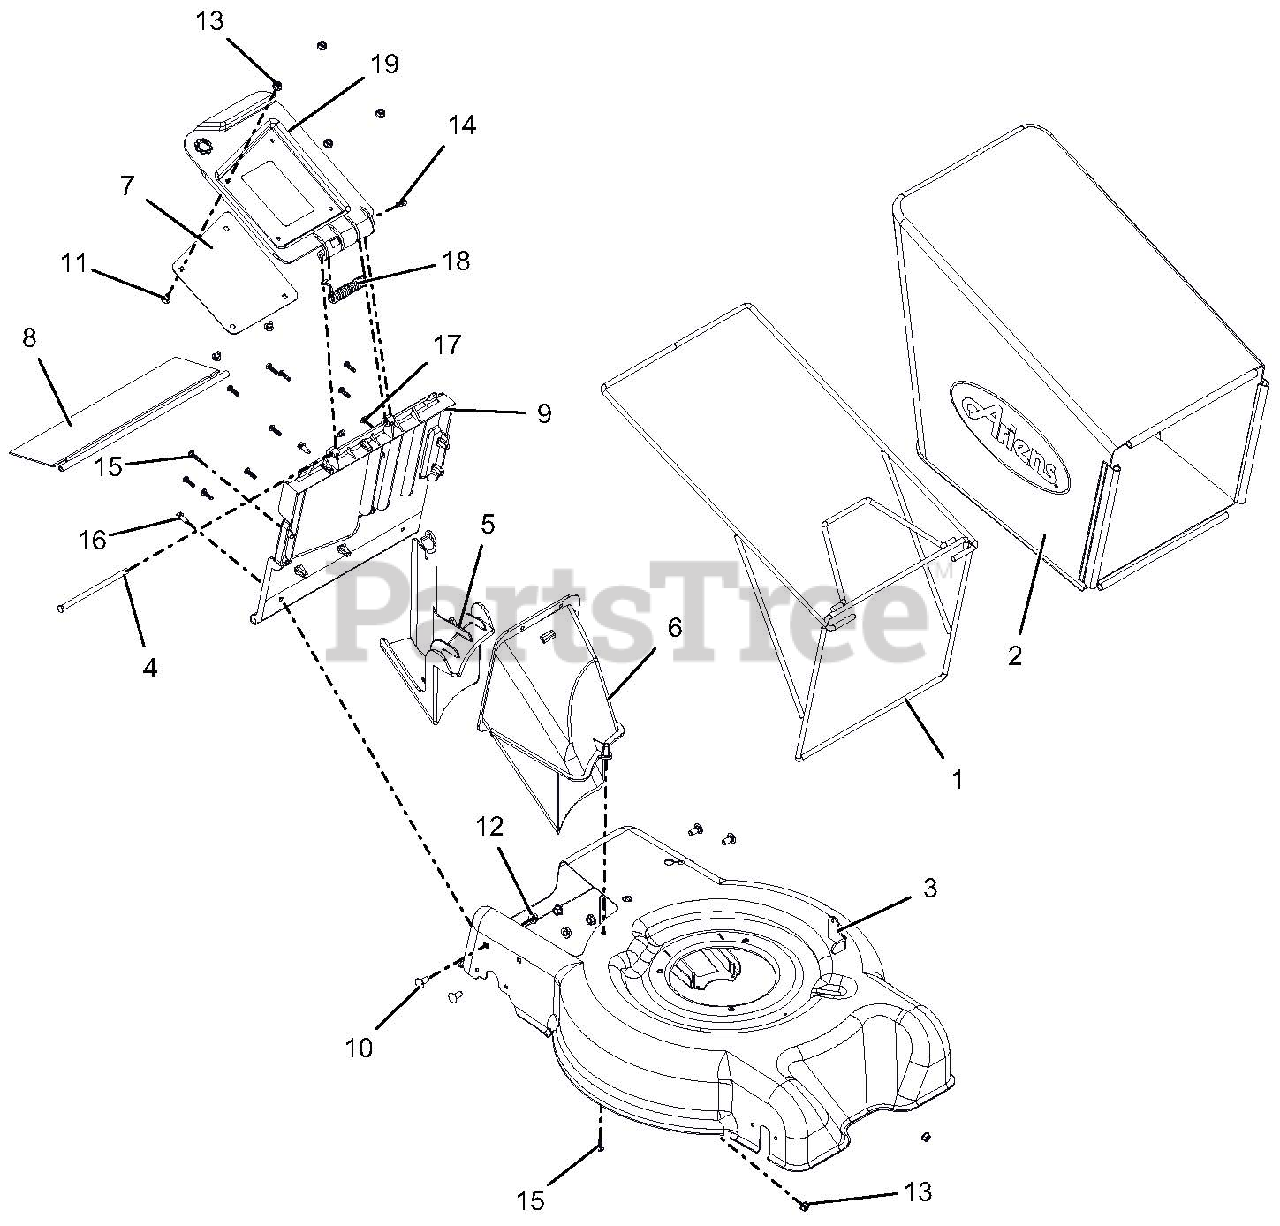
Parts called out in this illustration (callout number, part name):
1	FRAME, BAGGER
2	BAGGER, ARIENS LM
3	DECK W/ SAFETY DECAL
4	PIN, 5/16 X 5.80"
5	PLUG, MULCH
6	CHUTE, REAR DISCHARGE LM
7	PLATE, REAR DOOR
8	GUARD, REAR DECK
9	HANGER, REAR BAG
10	@BLT-RDHDSQNK .31-18X.75 G5YZ
11	@BLT-RDHDSQNK .25-20X.50 G5YZ
12	@NUT-LK-TOP-FLG .31-18 YWZC
13	@NUT-LK-TOP-FLG .25-20 YWZC
14	PIN-HAIR INT .08X.18X1.18 YWZC
15	SCR-TAP 12-14X.75PLSTITE @BLZC
16	@SCR-TAP .25-20X.62 HWH TR YWZ
17	PLUG,5/16 HOLE,.125 MATL PLSTC
18	SG-TORS .120X.68X3.09
19	REAR DOOR W/ SAFETY DECAL
